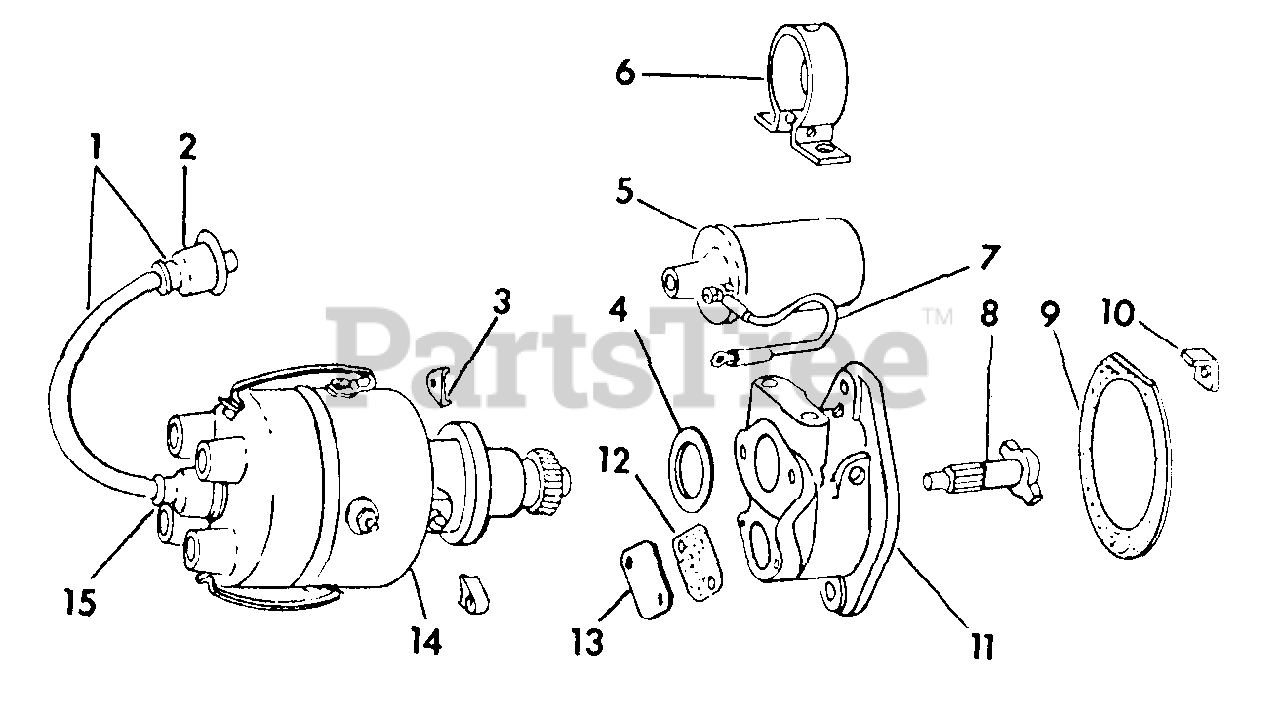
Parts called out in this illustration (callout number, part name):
1	CABLE, COIL TO DISTRIBUTOR W/NIPPLES
2	NIPPLE, IGNITION COIL
3	CLAMP, DISTRIBUTOR
4	GASKET, DISTRIBUTOR
5	PACKAGE, IGNITION COIL SERVICE
6	CLAMP, IGNITION COIL
7	CABLE ASSY, COIL TO DISTRIBUTOR PRIMARY
8	SHAFT ASSY, DISTRIBUTOR DRIVE
9	GASKET, DISTRIBUTOR DRIVE HOUSING
10	NOT USED IN THIS APPLICATION
11	PACKAGE, DISTRIBUTOR DRIVE HOUSING AND COVER SERVICE
12	GASKET, DISTRIBUTOR DRIVE HOUSING HOLE COVER
13	COVER, DISTRIBUTOR DRIVE HOUSING HOLE
14	DISTRIBUTOR ASSEMBLY
15	NIPPLE, DISTRIBUTOR CAP TERMINAL
